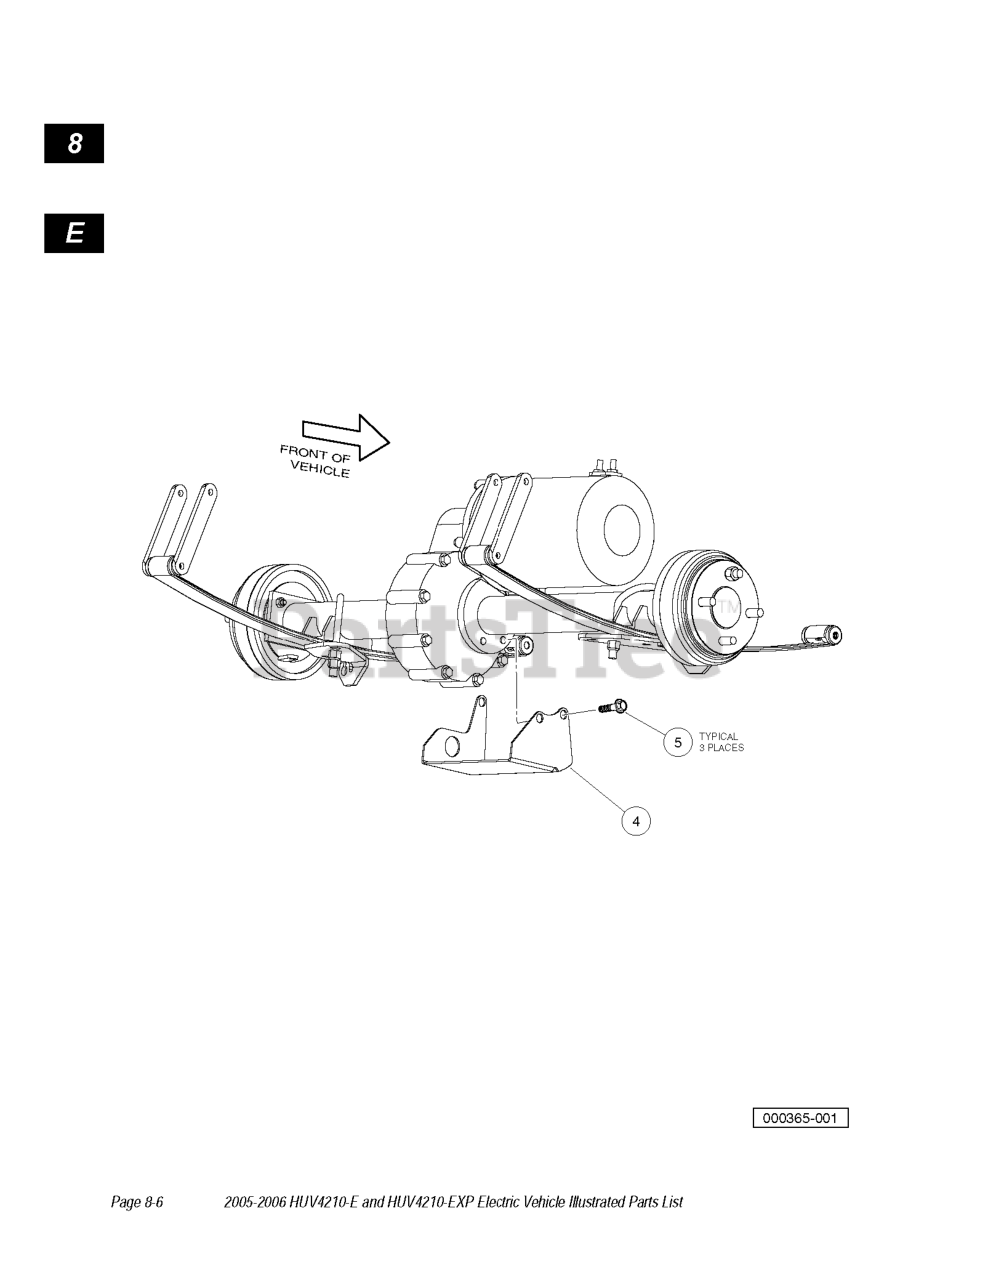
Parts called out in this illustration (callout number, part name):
1	Differential Guard Kit
3	SCREW M10-1.5X60MM HEX CAP
5	SCREW FLG HD M10X1.5X30
